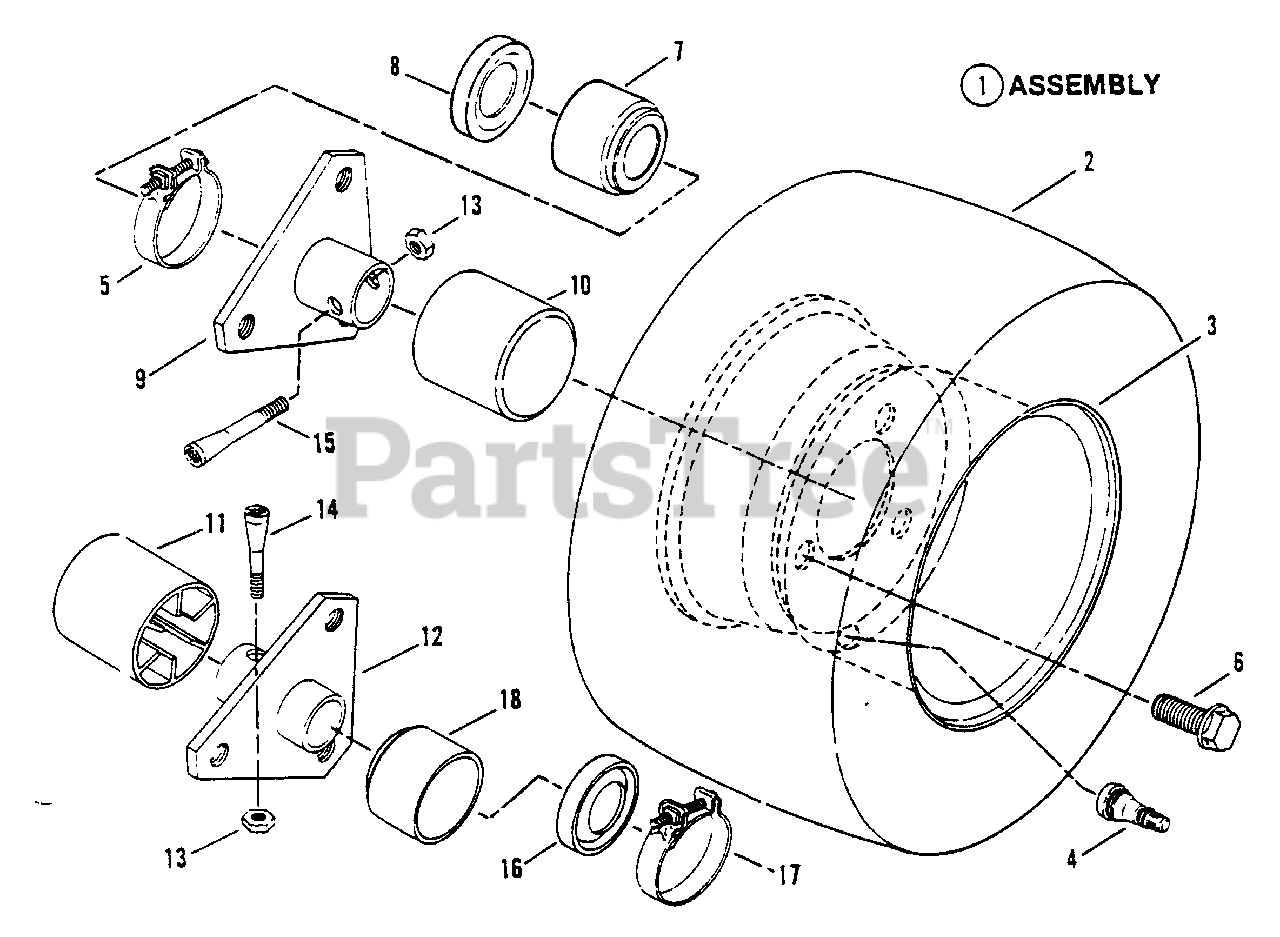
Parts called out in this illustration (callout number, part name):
1	ASSEMBLY, Rear Tire & Rim, 16x6.50-8
2	TIRE, Wide, 16x6.50-8
3	RIM, Wide 3 Hole, Grey
4	VALVE, Air (Snap-in)
5	CLAMP, Right Hand
6	BOLT, 1/2-20 x 3/4" Lug
7	BOOT, Right Hand
8	SEAL, Oil
9	HUB, Rear Wheel (Right Hand)
10	CAP, Hub
11	CAP, Hub (Left Hand)
12	HUB, Rear Wheel
13	NUT, 5/16-24 Hex Center Lock
14	BOLT, 5/16-24 x 1-5/8" Tapered (Left Hand)
15	BOLT, 5/16-24 x 2" Tapered (Right Hand)
16	SEAL, Oil (Left Hand)
17	CLAMP, (Left Hand)
18	BOOT, (Left Hand)
